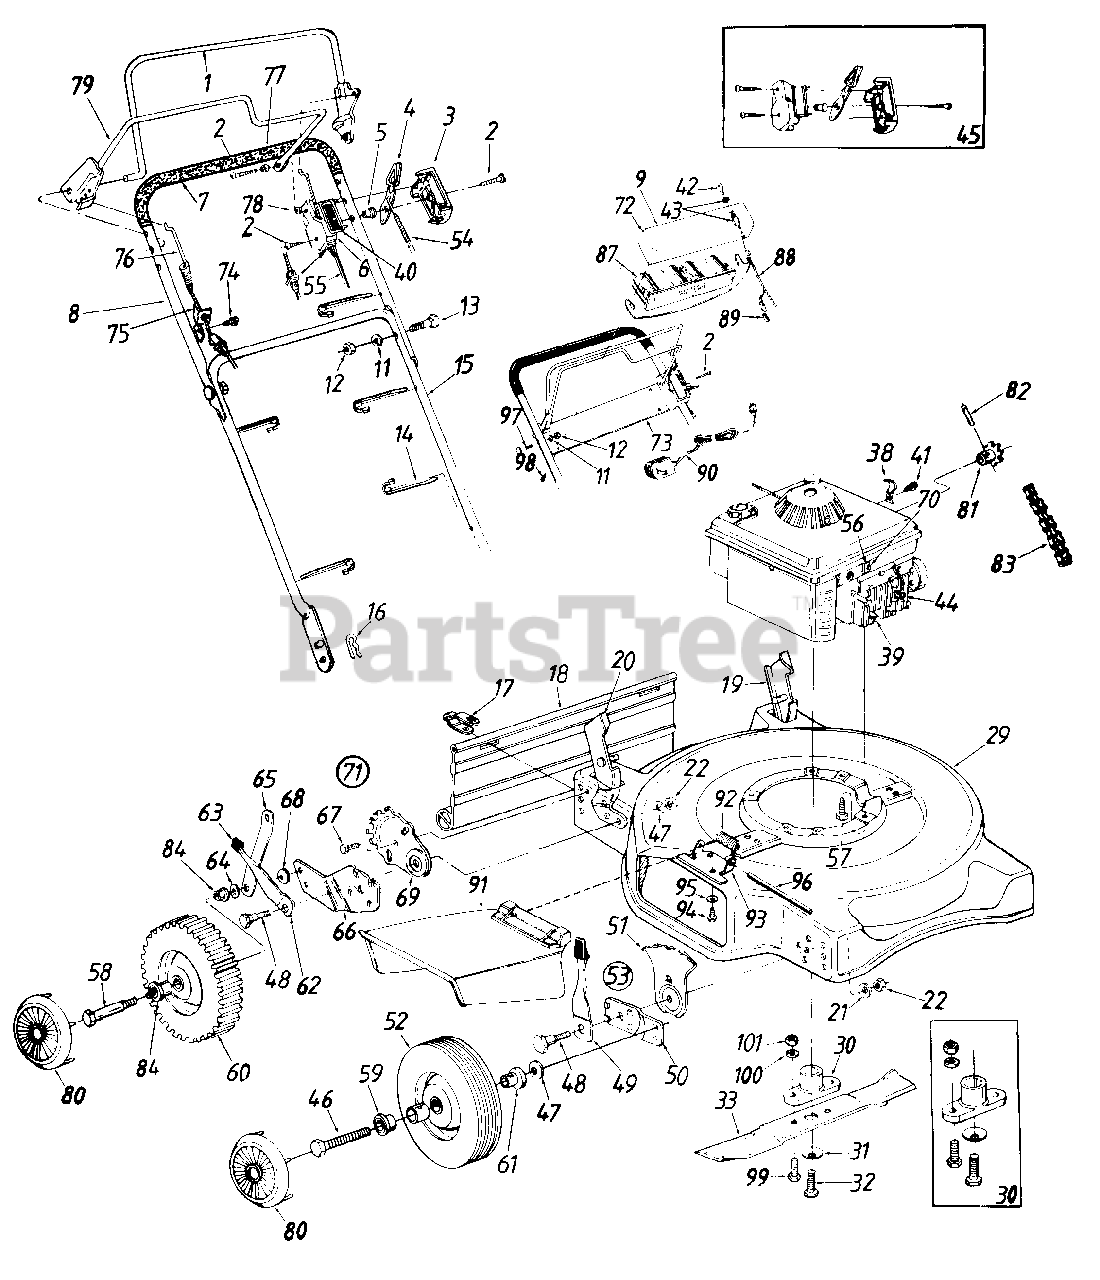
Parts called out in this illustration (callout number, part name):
1	Control Handle Ass'y.
2	Truss Mach. Scr. #12 x 1.5"
3	Control Panel Half
4	Throttle Control Lever
5	Control Disc Pin
6	Clutch Panel Half
7	Foam Grip
8	Upper Handle
9	Instruction Label-Handle
11	L-Wash. 5/16" I.D.
12	Hex Nut 5/16-18 Thd.
13	Curved Carriage Bolt 5/16-18 x 1.38" Lg.
14	Cable Tie
15	Lower Handle
16	Hairpin Cotter
17	Hinge Clip
18	Rear Flap
19	Handle Brkt. Ass'y.-L.H.
20	Handle Brkt. Ass'y.-R.H.
21	Bell-Wash. .39" I.D. x 1.38"
22	Hex Nut 3/8-16 Thd.*
29	22" Deck Ass'y.
30	Blade Adapter Kit
31	Bell-Wash..39" I.D.
32	Hex Bolt 3/8-24 x 1.5" Lg.
33	22" Blade
38	Cable Clamp
39	3.5 H.P. Engine-See Breakdown
40	Control Label-Throttle
41	Hex B-Tap Scr. #10 x .38"
42	Key
43	Key Switch
44	Spark Plug Boot
45	Kit-Control Housing Comp.
46	Front Axle Bolt
47	Bell-Wash. .400" I.D. x .88"
48	Shld. Bolt .50" Dia. x .357"
49	Spring Lever Ass'y. w/Knob
51	Height Adj. Plate
52	Front Wheel Ass'y. Comp.
53	Height Adj. Ass'y. Comp.-R.H.
54	Throttle Wire-53"
55	Control Cable-39"
56	Cable Clamp
57	Hex L-Wash. Hd. Scr. 3/8-16 x 1.0" Lg.
58	Rear Axle Bolt
59	Ball Bearing 1/2" I.D.
60	Rear Wheel Ass'y. Comp.
61	Ball Bearing 3/8" I.D.
62	Spring Lever
63	Spring Lever Knob
64	Fl-Wash. .531" I.D. x .93"
67	Hex AB-Tap 1/4-.62" Lg.
68	Bell-Wash. .380" I.D. x .88"
69	Index Plate
70	Hex B-Tap Scr. #10 x .62"
71	Rear Height Adj. Ass'y.-R.H.
72	Upper Battery Tray
73	Lower Battery Tray
74	Hex Wash. AB-Tap Scr. 5/16 x.75" Lg.
75	Cable Brkt.
76	Clutch Cable w/Spring-33"
77	Spacer .23" I.D. x .30" O.D.
78	Spr.-Wash. .206" I.D. x .448
79	S.P. Bail Ass'y.
80	Hub Cap
81	10 Tooth Sprocket Ass'y.
82	Spring Pin Spir. 3/16" Dia. x 1" Lg.
83	#48 Chain 1/2" Pitch 50 Links
84	Ball Bearing 1/2" I.D.
87	12 Volt Battery
88	Wire Harness
89	Plug
90	Battery Charger
91	Chute Deflector Ass'y.
92	Torsion Spring
93	Adapter Plate
94	Hex Self-Tap Scr. 1/4-20 x .5" Lg.
95	Bell-Wash. 1/4" I.D.
96	Hinge Pin
97	Curved Carr. Bolt 5/16-18 x 1.38" Lg.
98	Truss Mach. Hi-Riser Tap-Scr. 1" Lg.
99	Hex Bolt 3/8-24 x 1" Lg.
100	L-Wash. 3/8" I.D.
101	Hex Nut 3/8-24 Thd.
